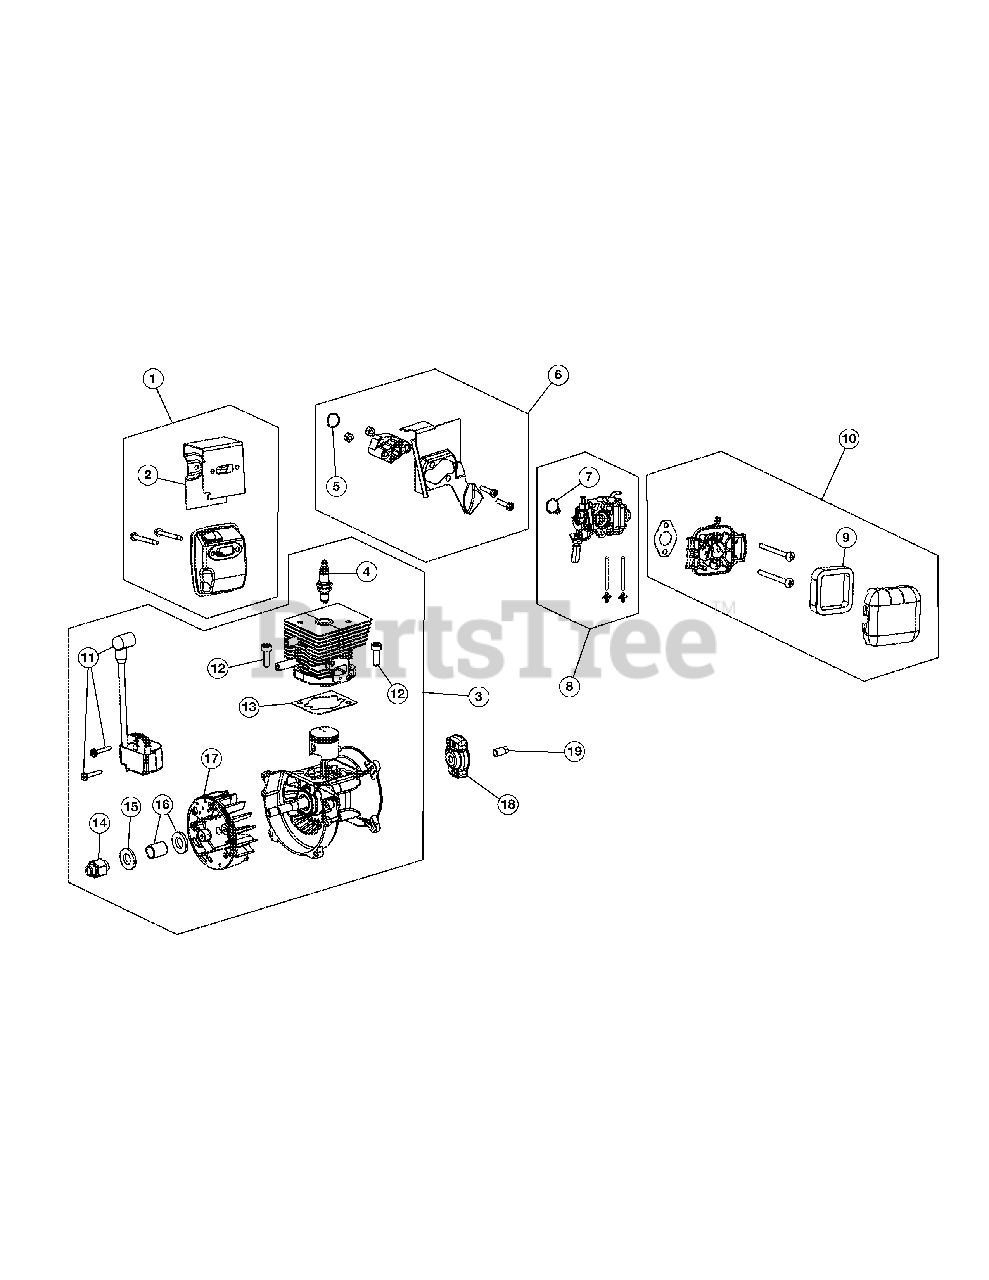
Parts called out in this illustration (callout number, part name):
1	Muffler Assembly (Incl. Ref No. 2)
2	Muffler Gasket
3	Shortblock Assembly (Incl. Ref No. 4 & 11-17)
4	Spark Plug
5	Insulator O-Ring
6	Insulator Assembly (Incl. Ref No. 5)
7	Carburetor Gasket
8	Carburetor Assembly (Incl. Ref No. 7)
9	Air Filter
10	Aircleaner Assembly (Incl. Ref No. 9)
11	Module Assembly
13	Cylinder Gasket
14	Flywheel Adapter
15	Washer
16	Bushing
17	Flywheel Assembly
18	Pawl Assembly
19	Electric Start Adapter
